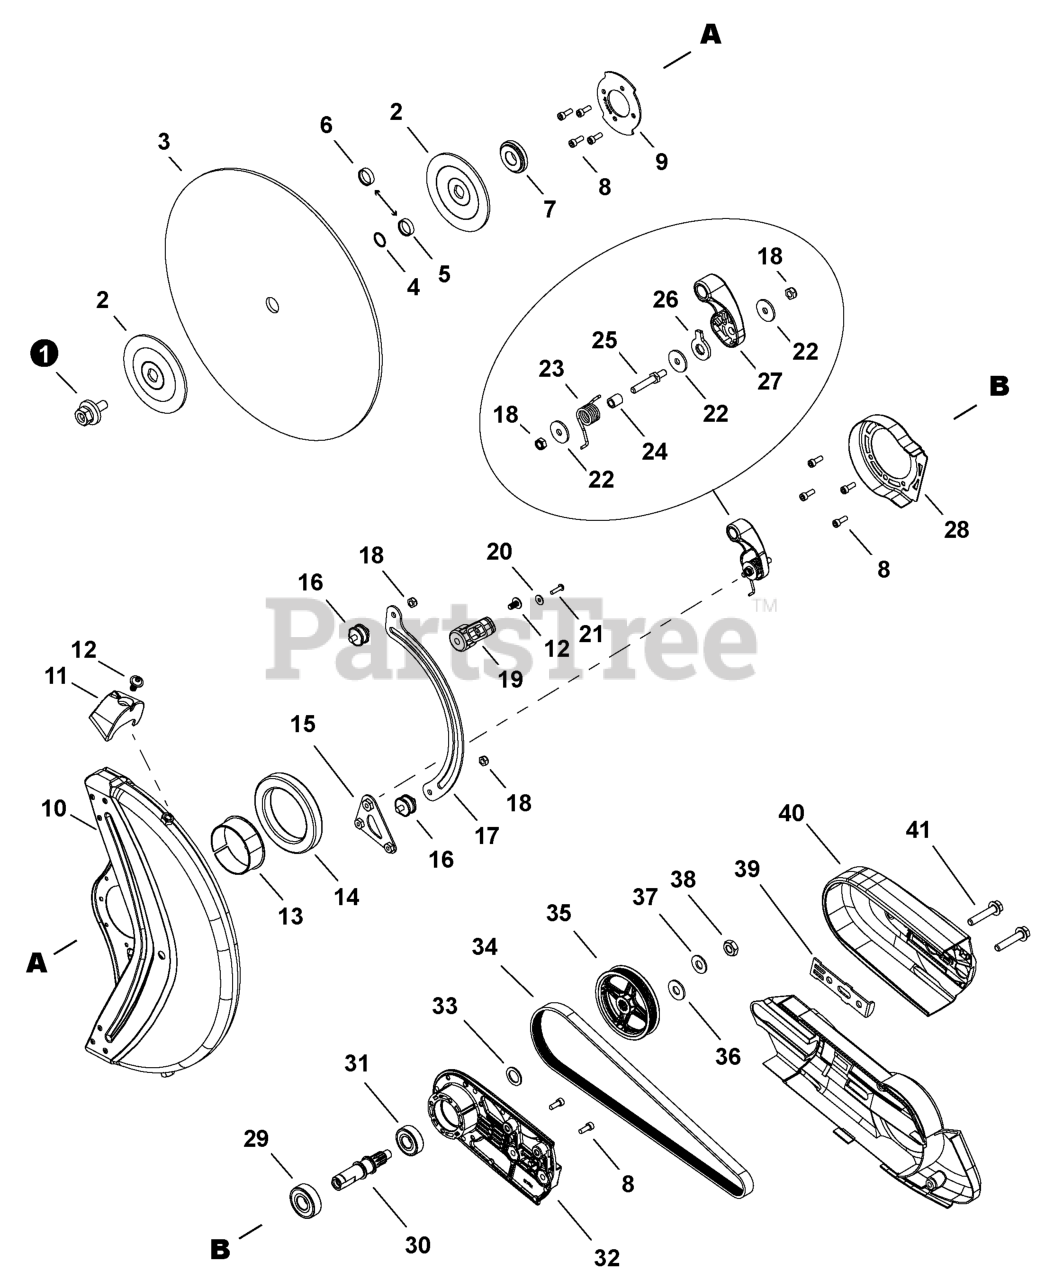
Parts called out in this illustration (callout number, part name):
1	BOLT ASSY
2	FLANGE, CUTTER
3	CUT-OFF WHEEL
4	RING, SNAP
5	ADAPTER, BLADE 20
6	ADAPTER, BLADE 25.4
7	COLLAR 18
10	COVER, CUTTER
13	RING, SLIDE
16	CUSHION 6
17	PLATE, ADJUST
18	NUT, LOCK
21	SCREW 4x16
22	WASHER 23x6.5x2 MM
23	SPRING, TORSION
28	COVER, SPRING
29	BEARING, BALL 6203
30	DRIVESHAFT
31	BEARING, BALL 6202 DDU
32	CASE ASSY
34	BELT, DRIVE
36	WASHER 11
37	WASHER, CONICAL
38	NUT 3N-10
39	PLATE, EYE
40	COVER, CUTTER ARM
